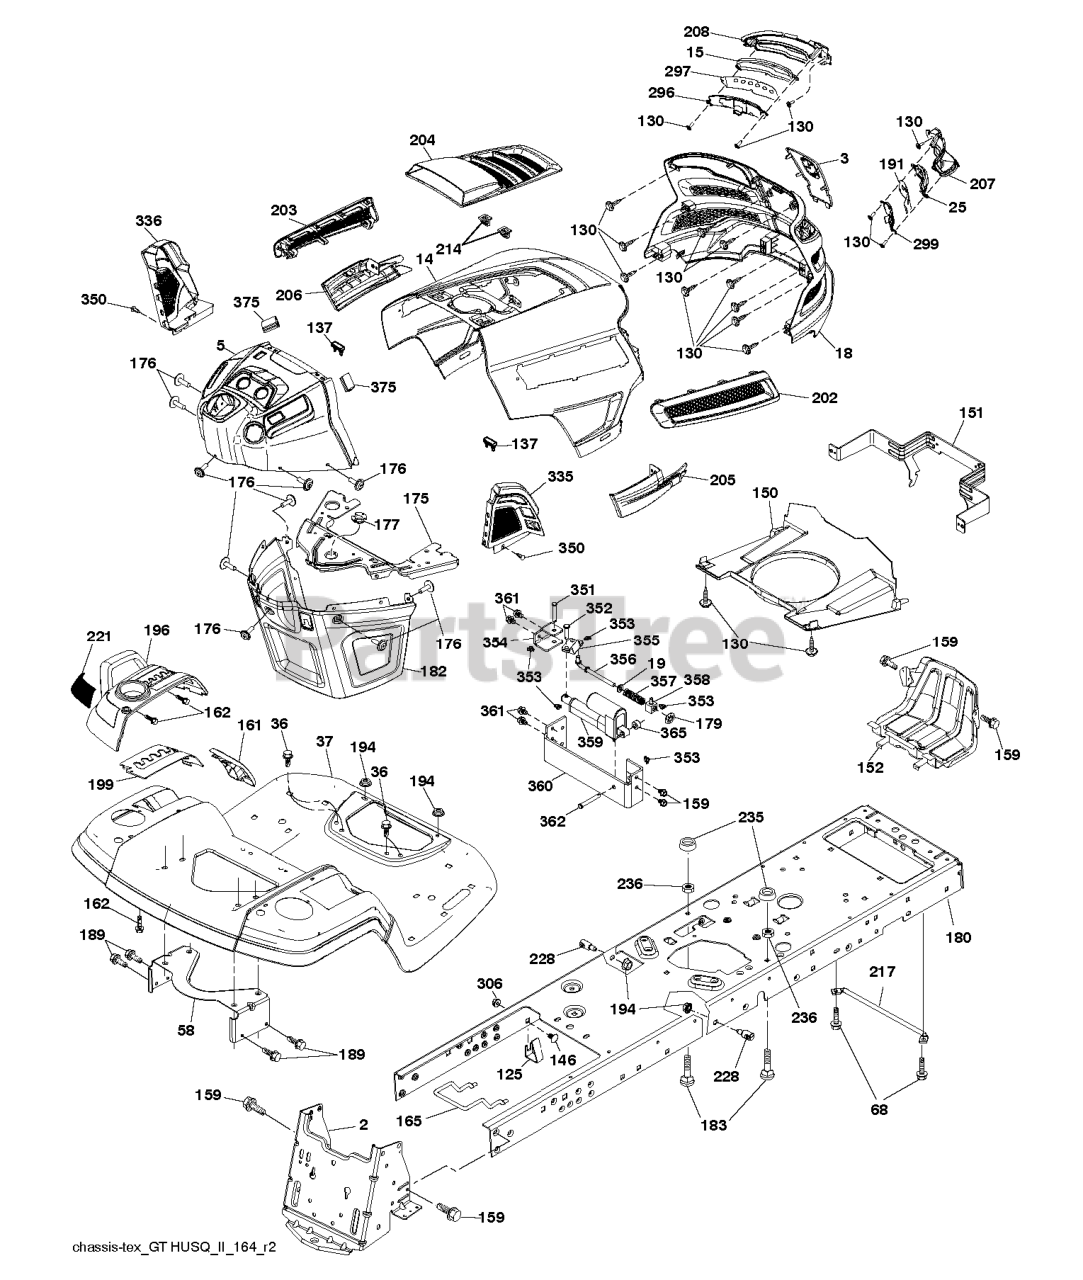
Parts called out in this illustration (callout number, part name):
2	DRAWBAR.STGT
3	APPLIQUE.SUBASM.GT.HUSQ.II
5	GT2.DASH.UPPER.W/BUMPER
14	HOOD.ASM.HUSQVARNA.GT.TEX.ORAN
15	LENS.HEADLIGHT.LH.GTII.2011
18	GRILLE.SUBSTRATE.2011.
19	WASHER
25	LENS.HEADLIGHT.RH.GTII.2011
36	SCREW 5/16"
37	FENDER.PNT.TX.GT.CH/FW/DL.HUSQ
58	BRKT.SUPPORT.FNDR/TANK
68	Screw 5/16-18 x 1/2 Hex, Self Tapping 5/16-18 x 1/2
125	CLIP.FUEL.LINE
130	SCREW.#10 X 0.750.BOS
137	BUMPER DASH
146	BOLT.RDHD.SHT.SQNK.3/8-16X5/8
150	AIR.DUCT.GTV.BLACK
151	BRACKET.PIVOT.HOOD.GT.HUSQ.II
152	SHIELD.BROWNING.PNT.GT.V2
159	SCREW, 3/8-16X3/4
161	CONSOLE.WINDOW.FUEL.HUSQ.GT
162	SCREW.HI-LO.CONSOLE
165	SUPPORT.TANK.REAR.B/TE
175	PLATE.CROSSMEMBER.HUSQ
176	SCREW.#10-24X5/8.RN.QU
177	BUSHING STEERING
180	CHASSIS.TEX.BOLTED
182	DASH.LOWER.COMMON.12V.ADAPTOR
183	BOLT.5/16-18X1-1/4 FULL THD
189	SCREW
191	INSERT.REFLECTIVE.RH.HUSQ.GTII
194	NUT LOCK HEX FLANGE 5/16-18
196	CONSOLE.ASM.DECKLIFT.HUSQGT.DL
199	PLATE.DECK.LIFT.HUSQVARNA.GT
202	VENT.SIDE.RH.GT.HUSQ.II.
203	VENT.SIDE.LH.GT.HUSQ.II.498
204	VENT.TOP.HUSQ.GT2
205	SIDE.TRIM.RH.GT.HUSQ.II
206	SIDE.TRIM.LH.GT.HUSQ.II.GRAY
207	BEZEL LIGHT.RH.GT.II.MYLAR
208	BEZEL LIGHT.LH.GT.II.MYLAR
214	CLIP.RETAINER.TINNER.
217	ROD.PIVOT.HOOD
221	REFLECTOR.LH.TEX GT HU
228	STUD.FASTNER.W/ANTI-ROTATE
235	SPACER FENDER
236	NUT.CENTERLOCK.5/16-
296	LED LIGHT.LH
297	INSERT.REFLECTIVE.LH.HUSQ.GTII
299	LED LIGHT.RH
306	NUT LOCK FLG 3/8-16 UNC
335	COVER.LOWER.DASH.RH.BLACK
336	COVER-LH.LOWER.DASH.GT2.BLACK
350	CLIP.X-MAS.TREE
351	PIN.CLEVIS.375X2.125
352	PIN.CLEVIS.(.375 X 1.25)
353	CLIP RETAINER
354	SUPPORT.BELLCRANK
355	BELLCRANK.PIVOT.LOCK.DIFF
356	LINK.LOCK.DIFF
357	SPRING.COMPRESSION
358	GUIDE.SWIVEL
359	ACTUATOR.ELECTRIC
360	BRACKET.ACUATOR
361	SCREW LT.3/8-46X5/8
362	PIN.CLEVIS.(.375 X 2.42)
365	SPACER.NYLON.75" X .4375
375	BUMPER CLIP-ON. DASH 1"
